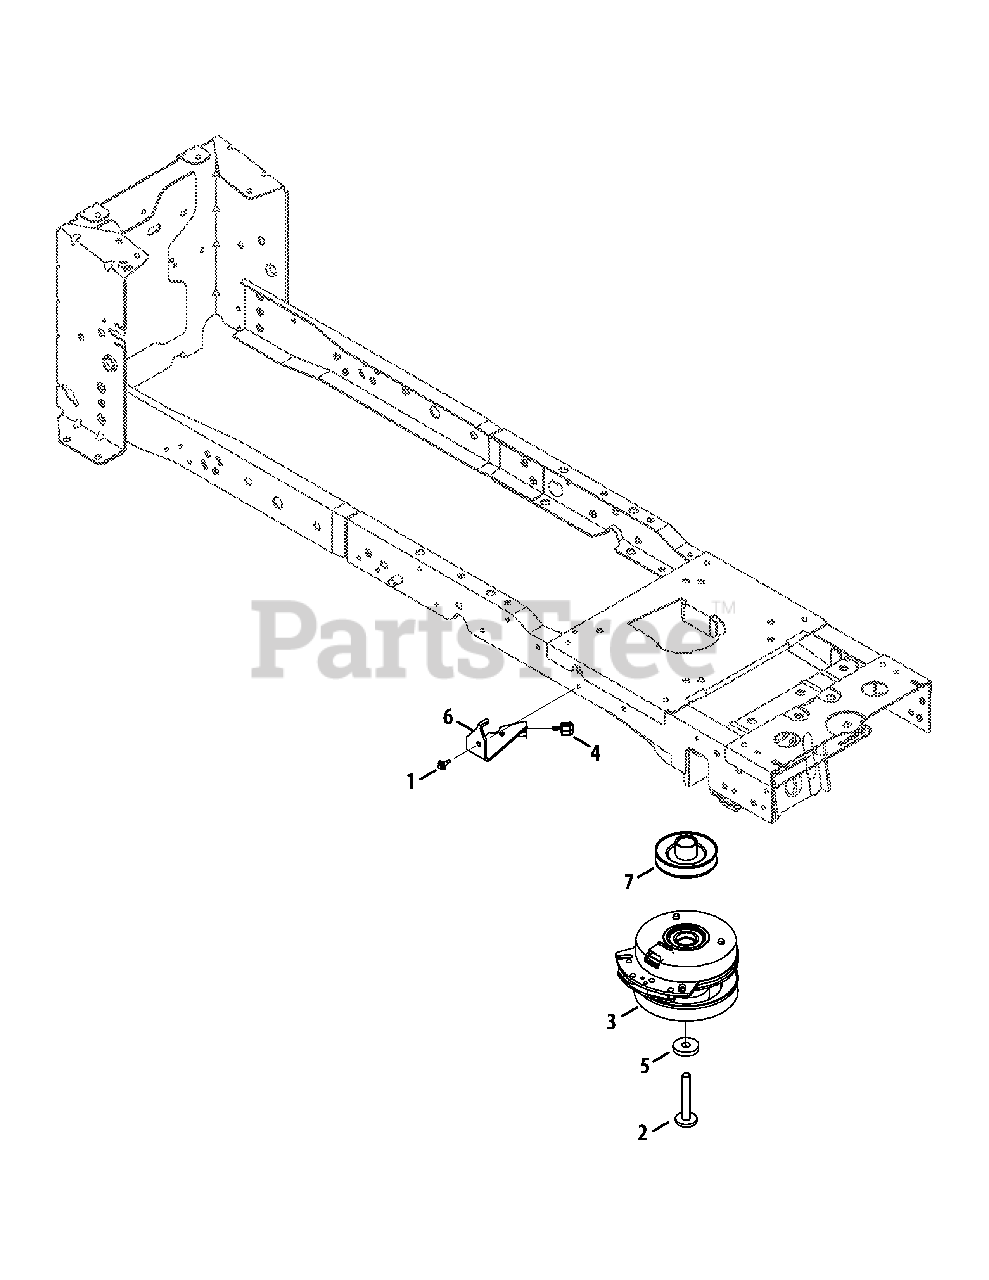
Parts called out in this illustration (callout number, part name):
1	Screw, M6-1 x .625
2	Hex Cap Screw, 7/16-20 x 3.50
3	Clutch, Electric PTO
5	Flat Washer, .450 x 1.375 x .250
6	Clutch Bracket
7	Engine Pulley
